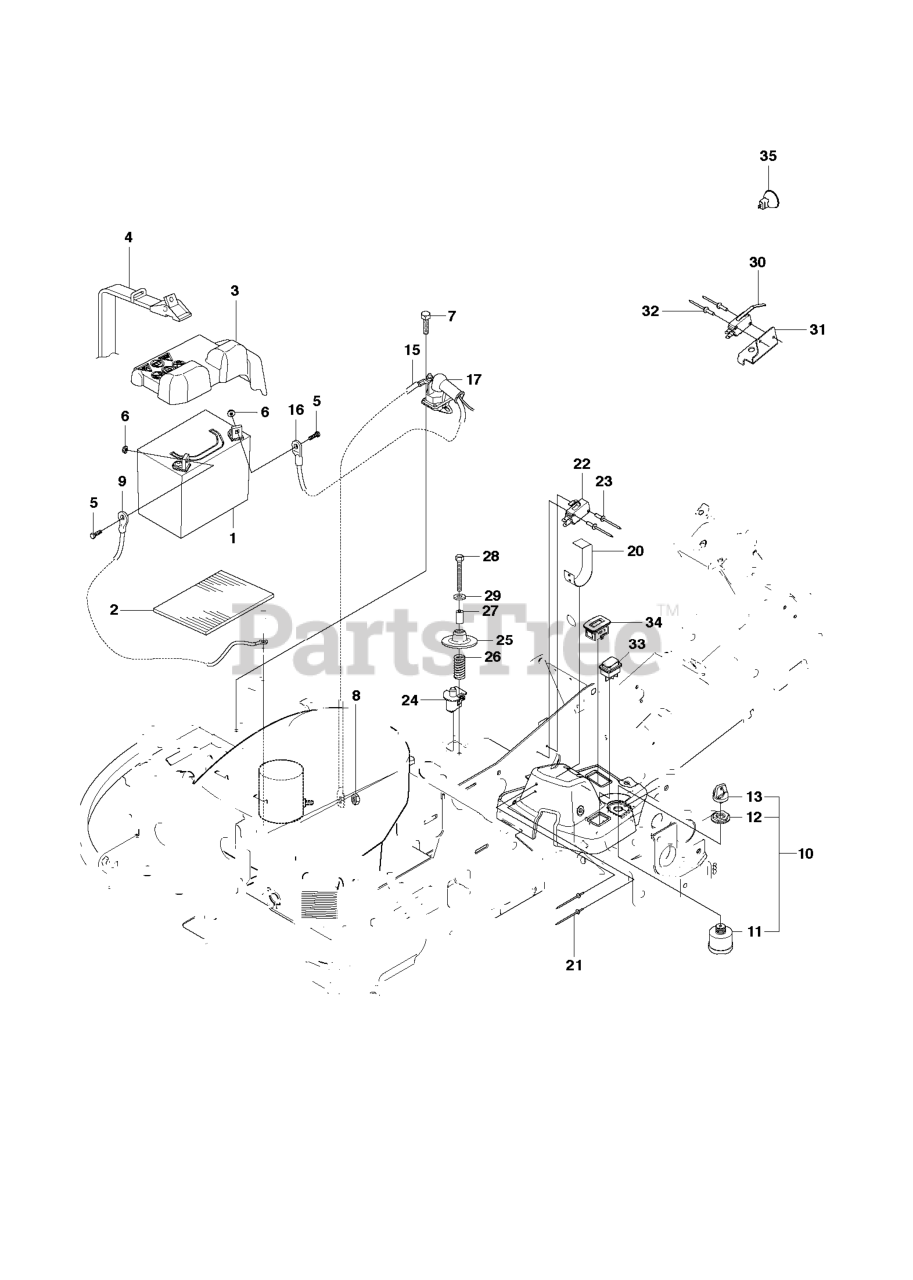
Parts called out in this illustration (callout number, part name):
5	SCREW EHHM
10	IGNITION SWITCH
11	IGNITION SWITCH
13	IGNITION KEY
22	%BRAKER
27	SPACER TUBE
28	SCREW
29	WASHER BRB 8.4X17
30	RP MICRO SWITCH
